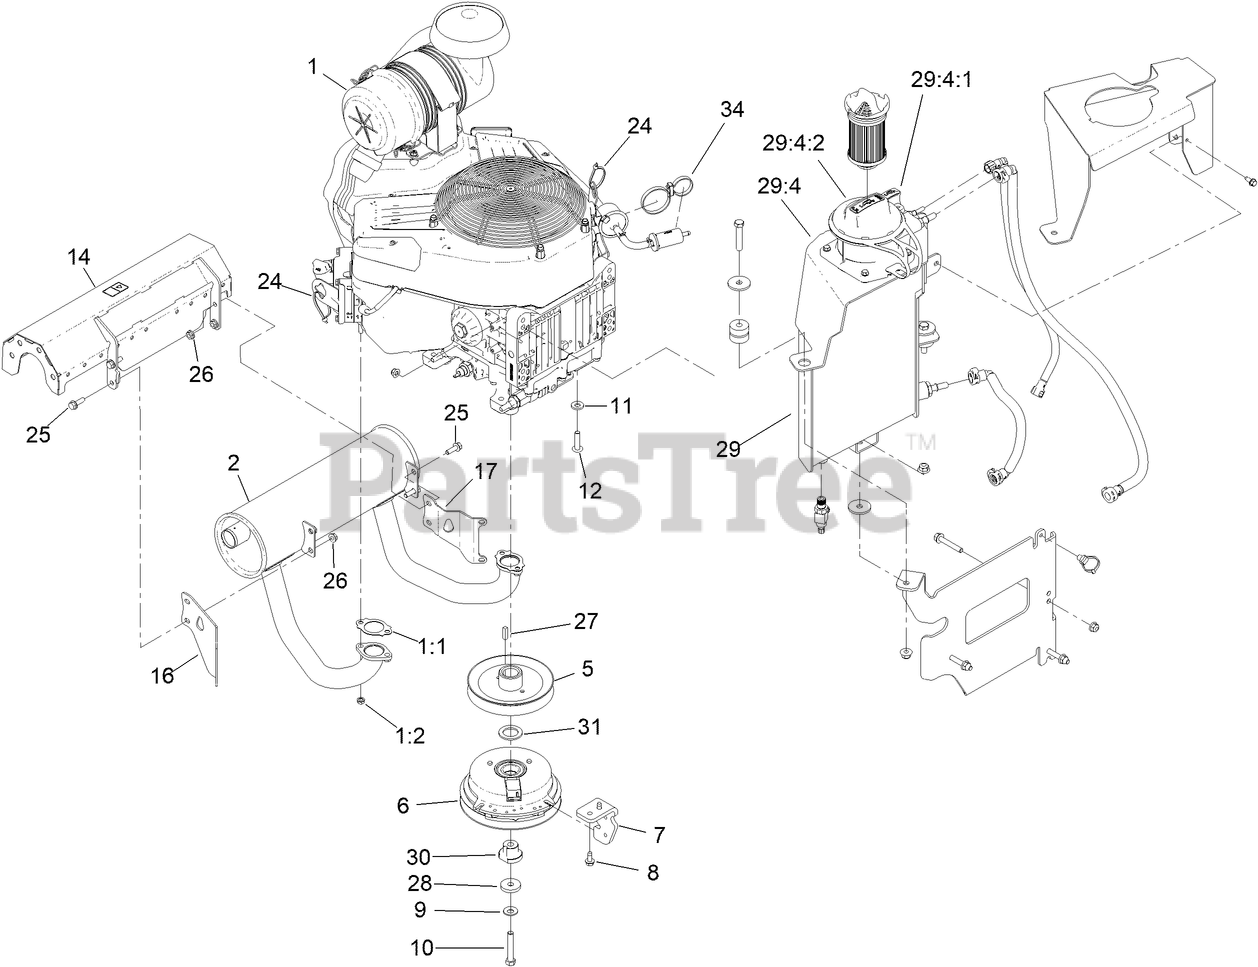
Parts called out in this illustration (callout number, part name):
1	ENGINE VANGUARD EFI
1:1	GASKET-EXHAUST
1:2	NUT-HEX
2	MUFFLER, BASCO 37HP
5	PULLEY
6	CLUTCH-200CMS
7	BRACKET, CLUTCH STOP
8	SCREW-HWHTF
9	WASHER-SPRING
10	SCREW-HH
11	WASHER-BELLEVILLE
12	SCREW-BHTF
14	MUFFLER GUARD ASM
16	BRACKET-MUFFLER
17	BRACKET-MUFFLER
24	TIE-CABLE
25	SCREW-HHF
26	NUT-HF
28	WASHER
29	OIL GUARD ASM
29:4	RESERVOIR-OIL
29:4:1	OIL DIPSTICK ASM
29:4:2	OIL TANK CAP ASM
30	SPACER, D-DRIVE
31	WASHER-THRUST
34	TIE-CABLE, DOUBLE LOOP
